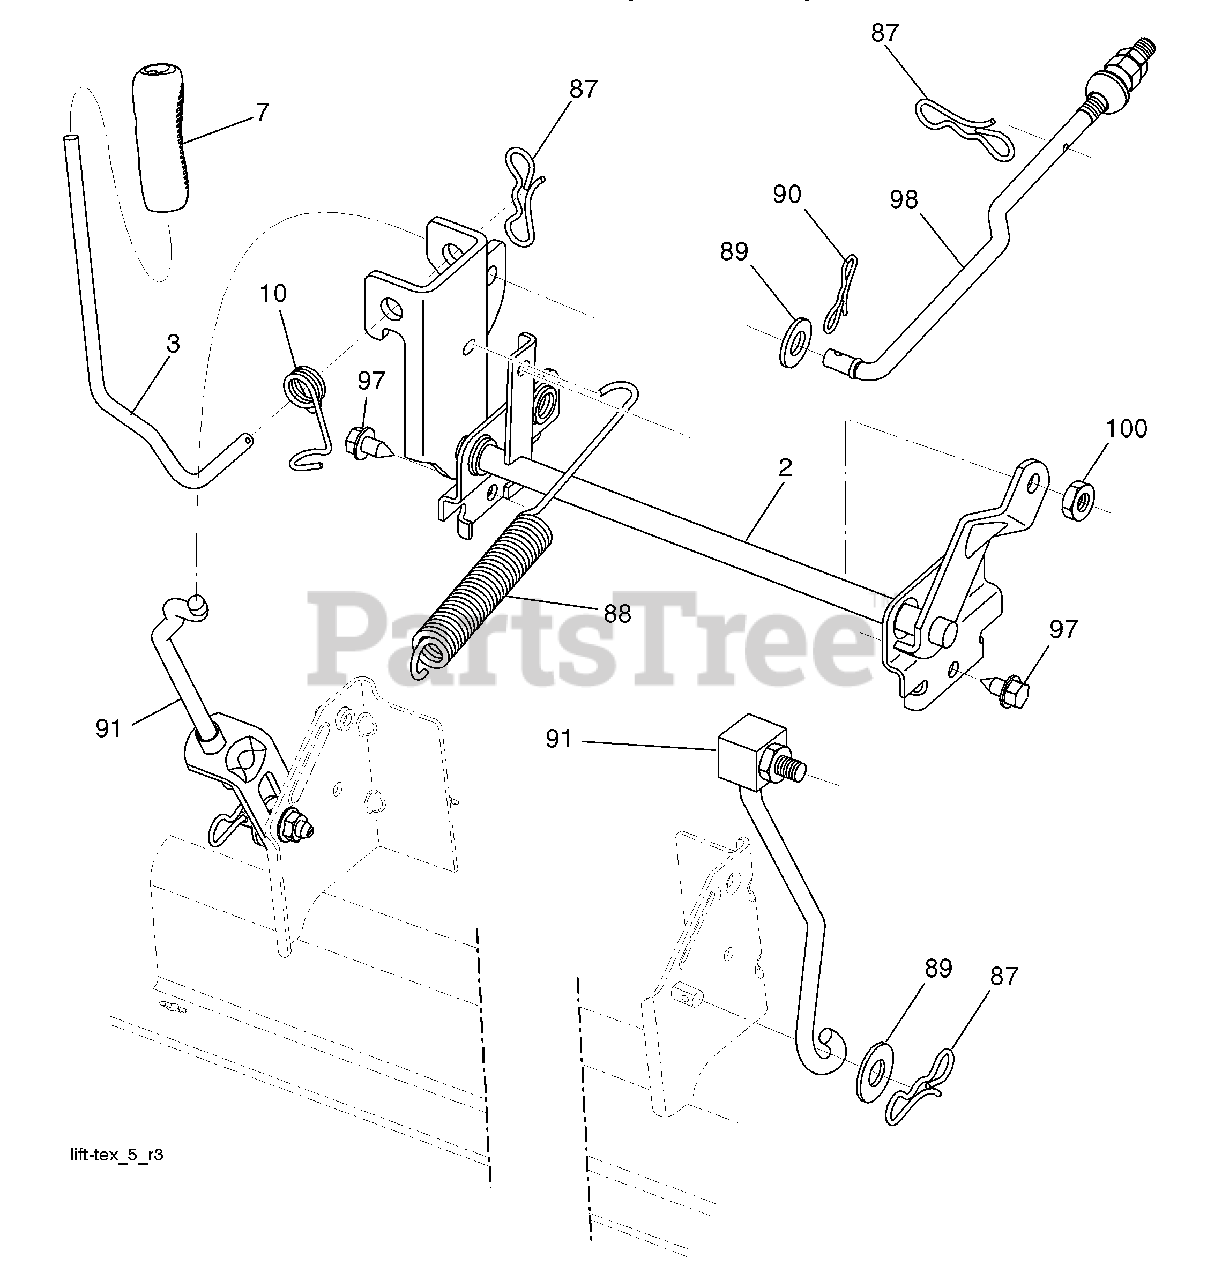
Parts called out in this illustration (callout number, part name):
2	Shaft Asm., Lift
3	Lever Asm., Lift RH
7	Grip, Lever
10	Spring Torsion
87	Pin Cotter 7/16 Bow Tie Lock
88	Spring Lift Assist
89	Washer Clear Zinc
90	Pin Cotter 5/16 Bow Tie Lock
91	Link Lift Susp Mower Rear
97	Screw 3/8-16 x .75 Smgml Tap/R.Z
98	Link Lift Susp. Front Mower
100	Nut Center Lock 3/8-16 unc
